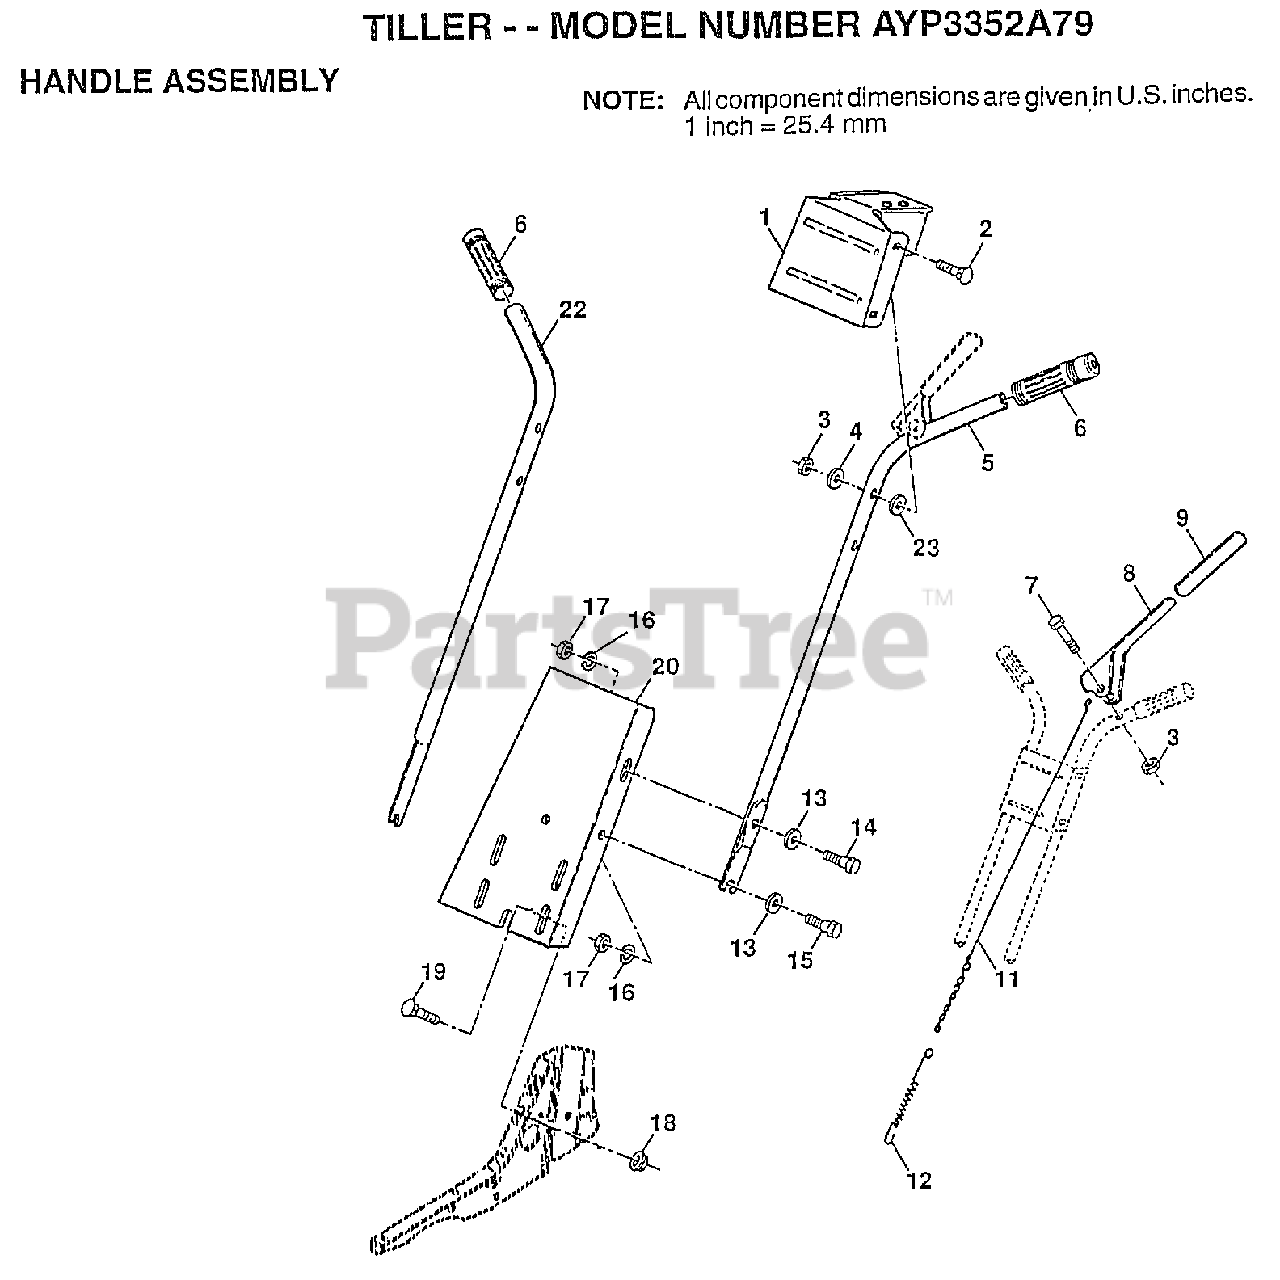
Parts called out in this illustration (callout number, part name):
1	HANDLE BRKT
2	BOLT
4	WASHER
5	HANDLE LH
7	BOLT.HEX.5/16-1.5
9	GRIP T
12	SPRING EXT TI
13	WASHER
15	BOLT
16	LOCKWASHER
17	NUT.HEX.5/16-18
18	NUT
19	BOLT
20	PANEL. HANDLE
22	HANDLE RH
23	WASHER
